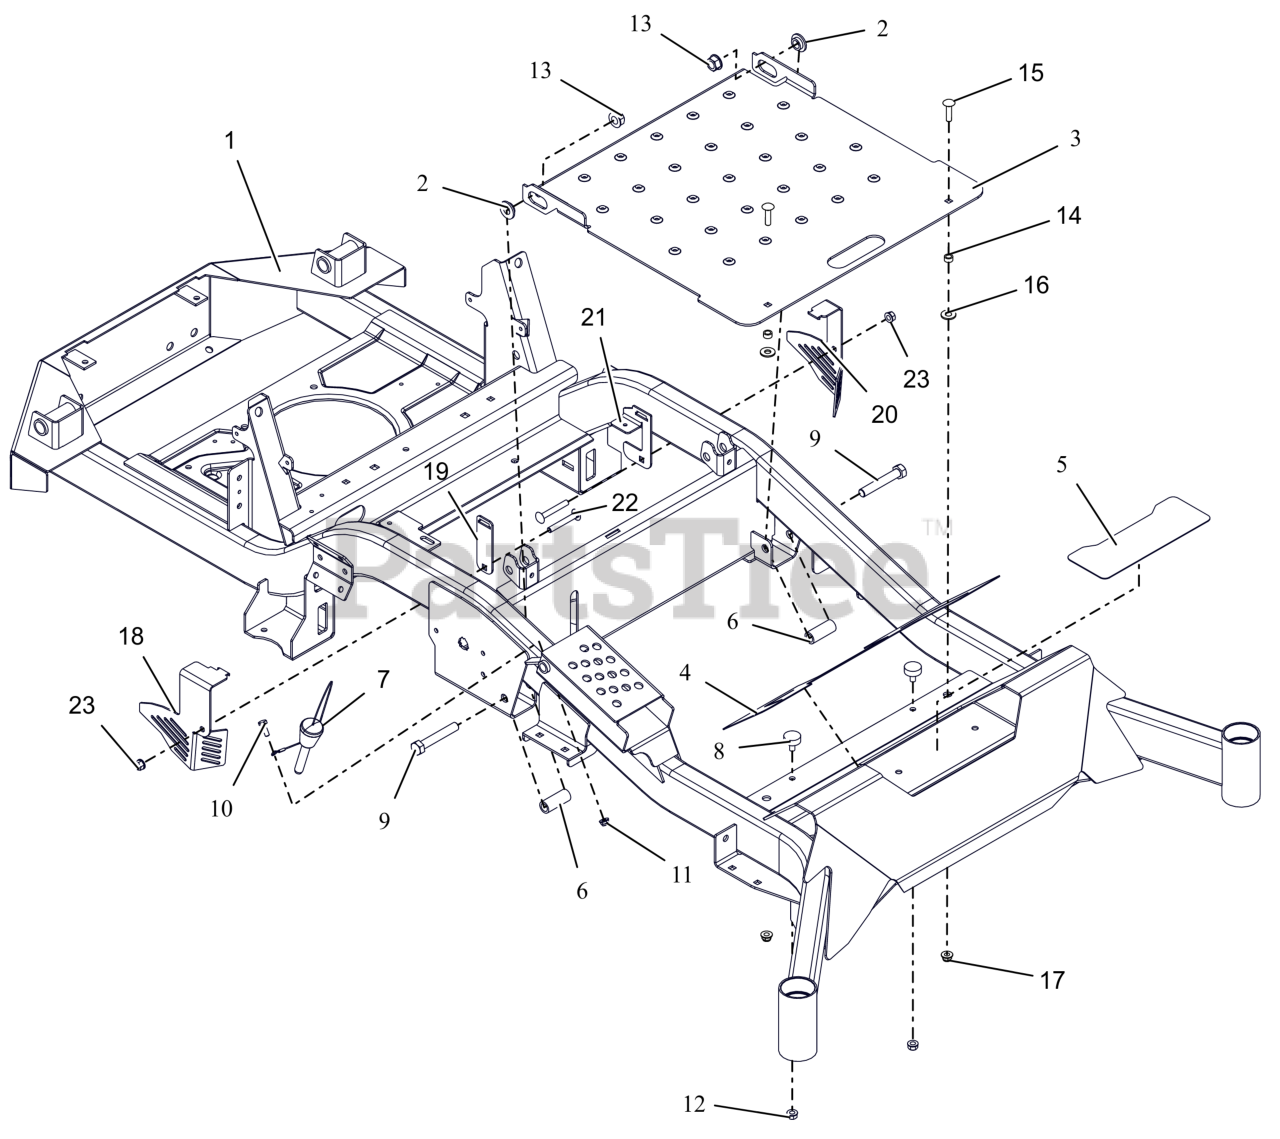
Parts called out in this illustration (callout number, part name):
1	APEX 60"FRAME W/SAFTETY DECALS
2	BSHG-FLG .515X.750X.395X1.120
3	PANEL, ACCESS
4	GRIP, FRONT
5	GRIP, STEP
6	SPACER, .515X.75X1.83
7	PIN, MAGNETIC .50X2.50
8	BUMPER, RUBBER
9	BLT, HEX .50-13X3.00 G5 ZCC
10	BLT, HEX .25-20X.75 G5 ZCC
11	NUT,NYL-FLG .25-20 GF ZCC
12	NUT,SPNLK-FLG .31-18 G5 ZCC
13	NUT-LK-TOP-FLG .500-13 GF ZCC
14	BSHG-SLV .344 X .500 X .260
15	BLT, RHSSN.31-18X1.25 G5 ZCC
16	WSHR,FLT .375X.875X.083 ZCC
17	NUT,LK-NYL-FLG .31-18 G5ZC120
18	GUARD, TRANSAXLE FAN - RH
19	BRKT, TRANSAXLE FAN GUARD
20	BRKT, TRANSAXLE FAN GUARD-LH
21	MOUNT, TRANSAXLE GUARD
22	BLT, RHSSN.31-18X2.25 G5 ZCC
23	NUT,LK-CTR-FLG .31-18 GF ZCC
